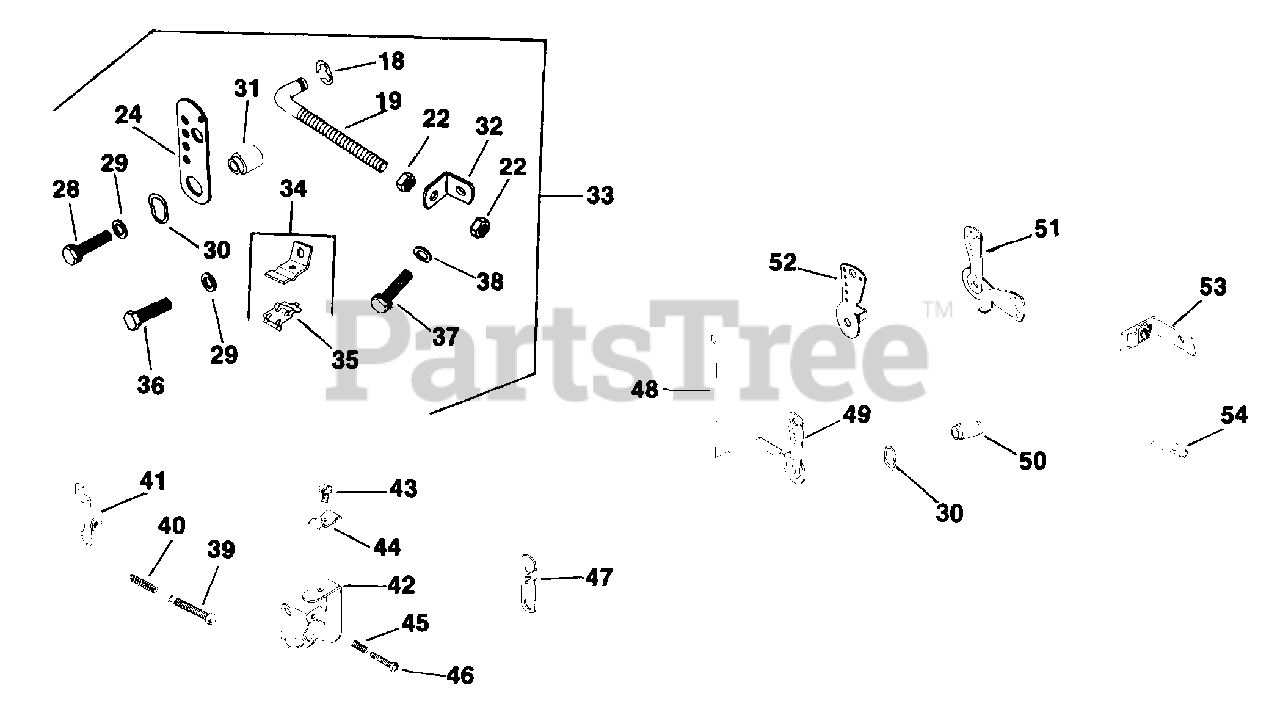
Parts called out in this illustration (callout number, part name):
18	RETAINER
22	NUT, MACH SCREW #10-32 GRD 2 USE 25 100 18-S
24	BRACKET
29	WASHER, FLAT 1/4" (O.D. 1/2")
30	WASHER, SPRING 11/32"
32	BRACKET, ADJUSTING SCREW - DISCONTINUED
34	BRACKET
43	SCREW - DISCONTINUED
